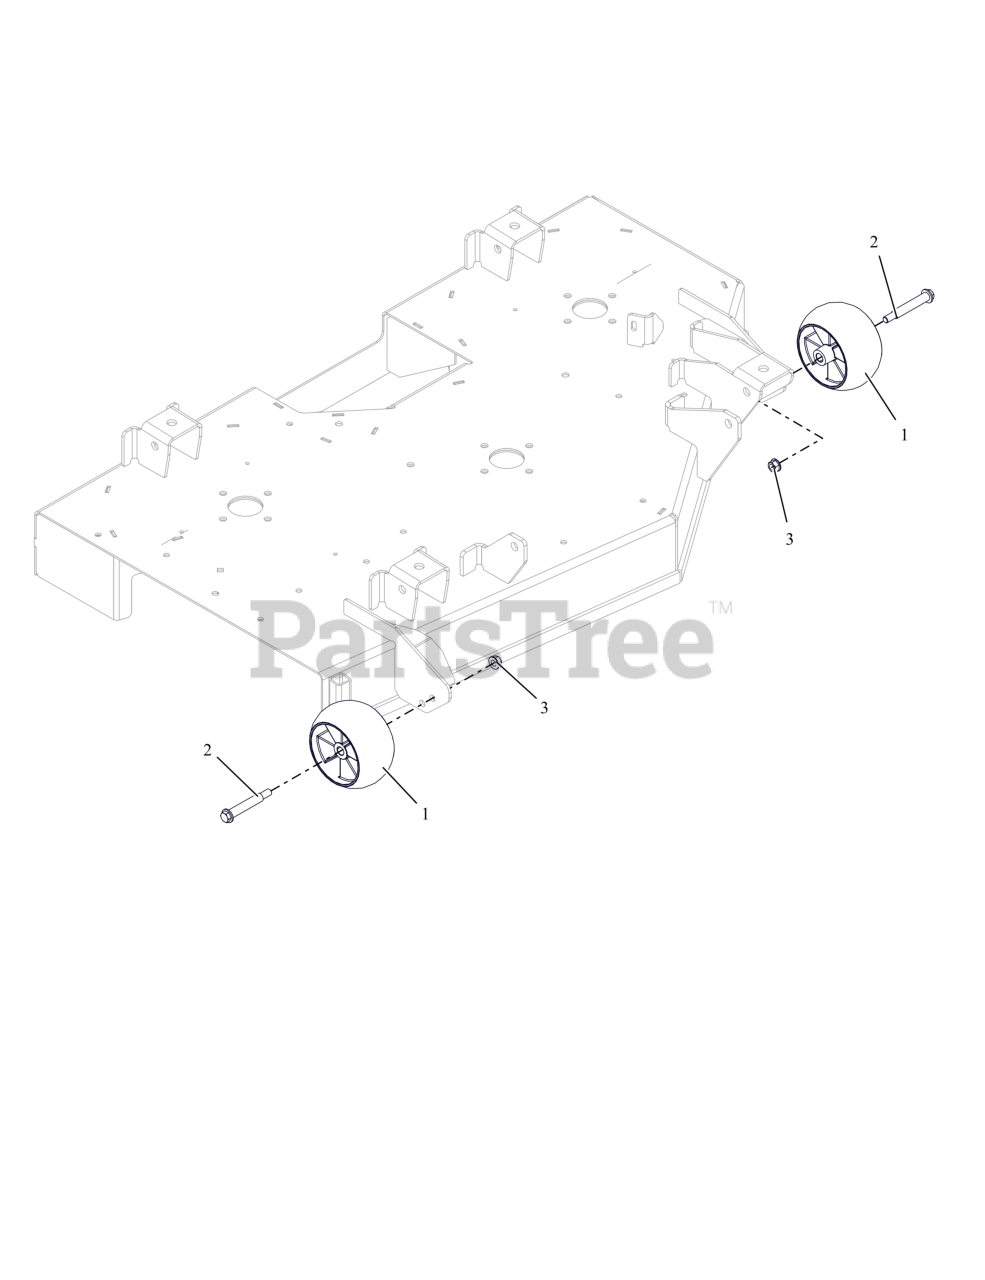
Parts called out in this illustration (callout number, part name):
1	ANTI-SCALP WHEEL - 5X OS
2	BLT-SHLDR .38-16X2.50 HWH G5
3	NUT-LK-CTR-FLG .375-16 GF ZCC
